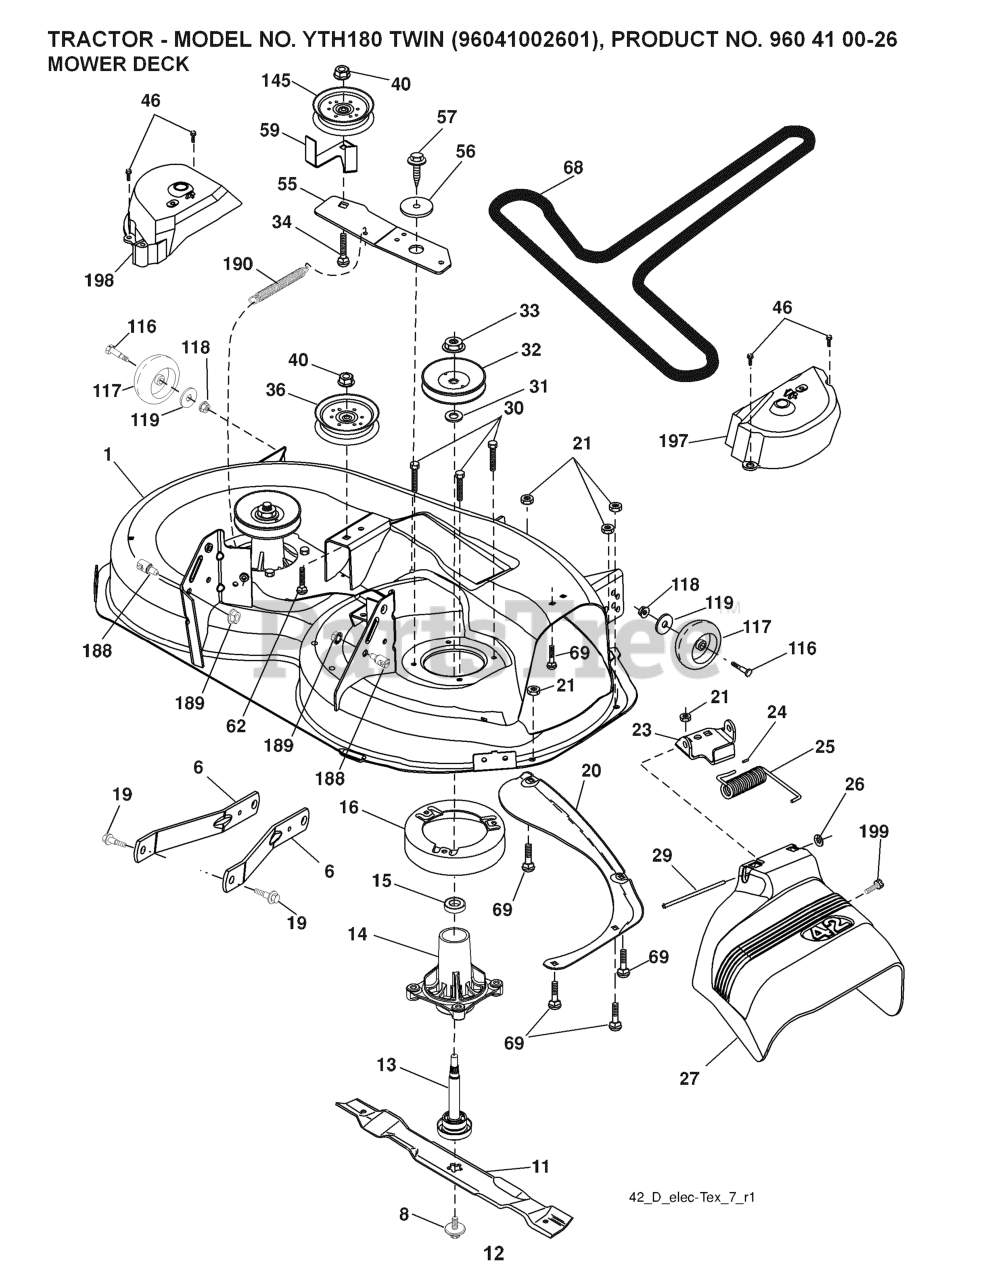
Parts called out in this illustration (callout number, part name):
1	DECK.WELDMENT.42"
6	ARM.SUSPENSION.MOWER.R
8	BOLT.WASHER.ASM.7/16-2
11	42" HI-LIFT BLADE
13	SHAFT.ASM.MDRL.N/GREASE.38
14	RP.HOUSING.MANDREL.4PT.
16	STRIPPER.MANDREL.ROUND.BLACK
19	BOLT.SHOULDER
20	BAFFLE.VORTEX
21	LOCKNUT
23	BRKT.DEFLECTOR.38"2005+
24	CAP-SLEEVE LT
25	SPRING.TORSION.DEFLECT
26	NUT PUSH M
29	ROD.HINGE
30	SCREW, WASHER HEAD
31	WASHER.SPACER.MANDREL
32	PULLEY/MANDREL
33	NUT.FLANGE.LOCK.TOP
34	BOLT.3/8-16X1.50
36	PULLEY.IDLER.48"PRIMARY
40	NUT LOCK FLG 3/8-16 UNC
46	SCREW.1/4-20X5/8
55	IDLER.ARM
56	SPACER.RETAINER
57	SCREW 3/8-16X1
59	GUARD, BELT
62	BOLT
68	BELT V SECONDARY
69	BOLT
116	BOLT M
117	WHEEL.GAGE.HALF.SPOKED
118	LOCKNUT
119	WASHER.5/16.FLAT.STE.STD.
145	PULLEY.IDLER.2006
188	STUD.FASTNER.W/ANTI-ROTATE
189	NUT LOCK HEX FLANGE 5/16-18
190	SPRING.MOWER.DRIVE.ELECTRIC
199	SCREW 3/8-16X1/2
